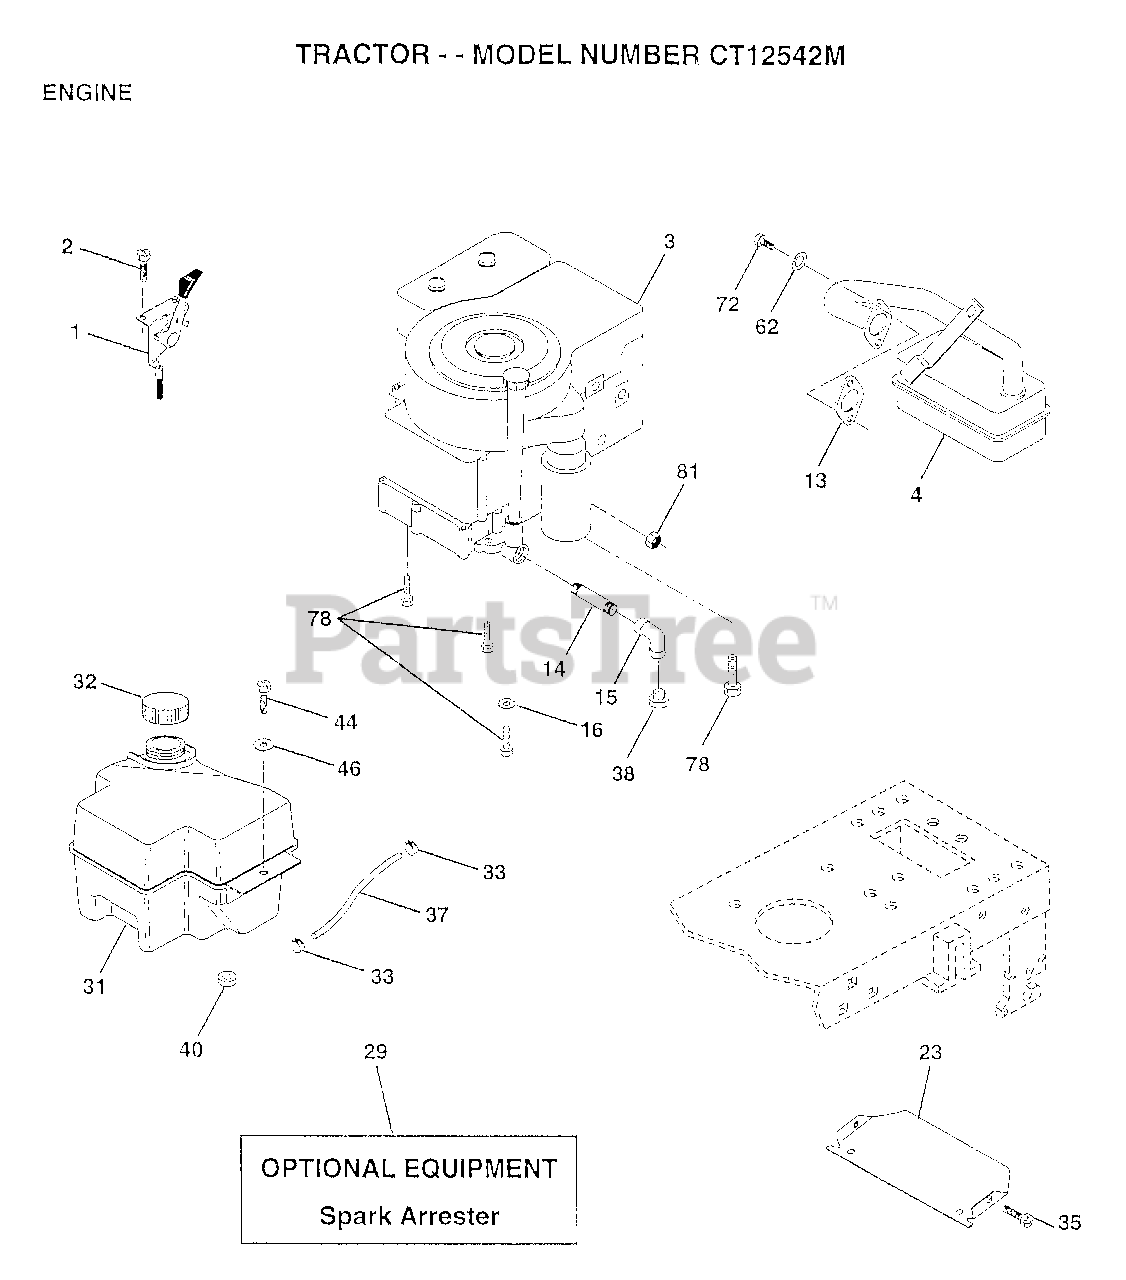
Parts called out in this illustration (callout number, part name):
1	CONTROL THROTTLE
2	SCREW LT
4	MUFFLER
13	GASKET ENG 1 313 LD TIN PLATED
14	PIPE NIPPLE
15	ELBOW
16	LOCKWASHER
23	SHIELD-HEAT
32	CAP ASM FUEL
33	HOSE CLAMP
35	SCREW
37	LINE FUEL
44	SCREW HEX CRT
46	WASHER
62	LOCKWASHER
72	SCREW
78	SCREW
81	NUT
